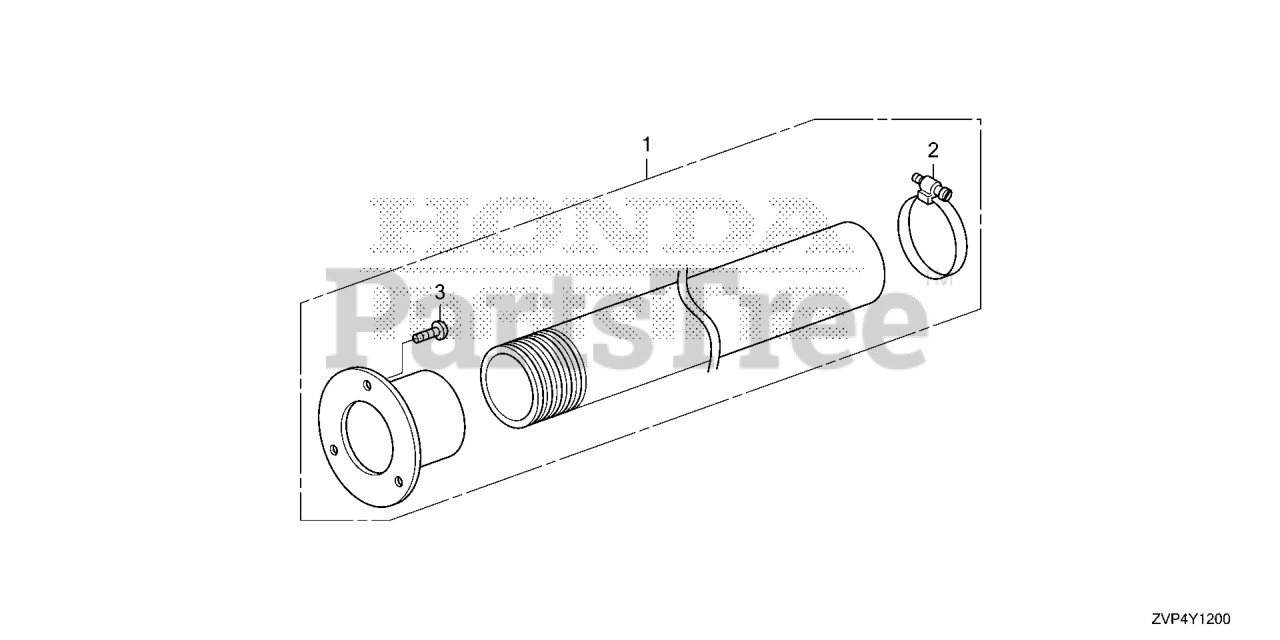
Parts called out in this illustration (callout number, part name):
1	HOSE KIT, RIGGING
2	CLAMP
3	SCREW, TAPPING
